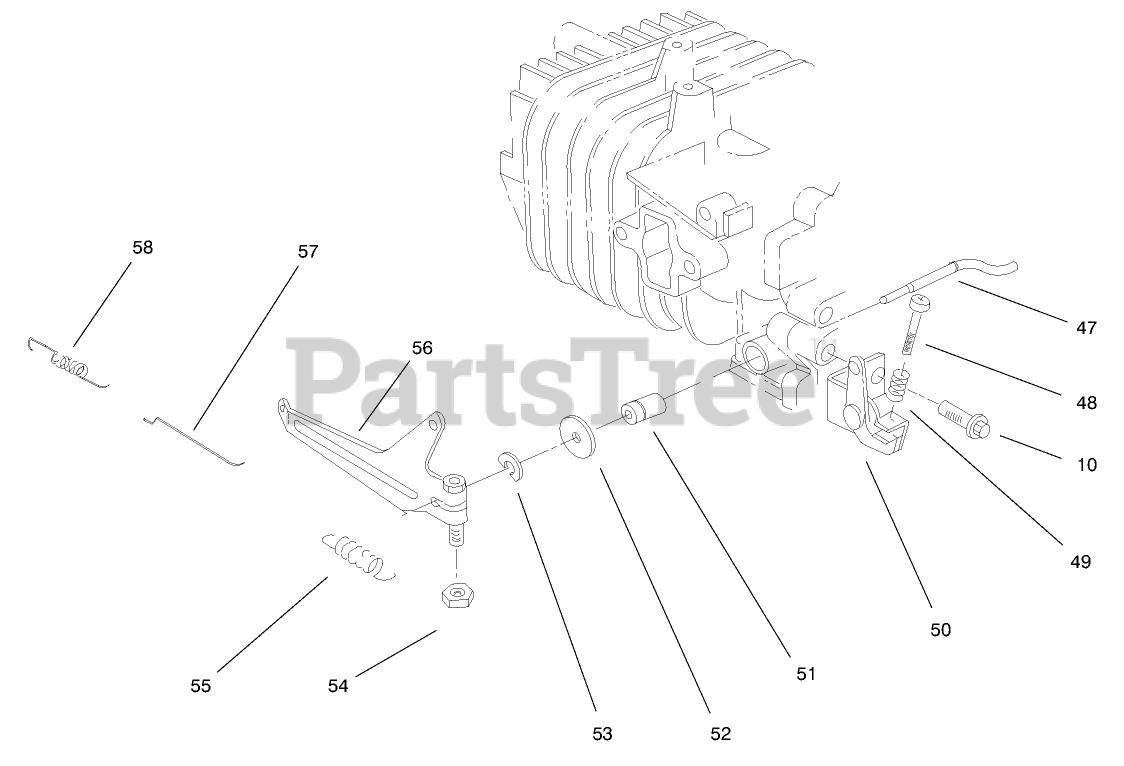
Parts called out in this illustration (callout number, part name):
47	SHAFT
48	SCREW
49	SPRING
50	GOV SPR BRKT
51	SEAL-OIL
52	WASHER
55	GOV SPRING
56	GOVERNOR ARM
57	CARB ROD
